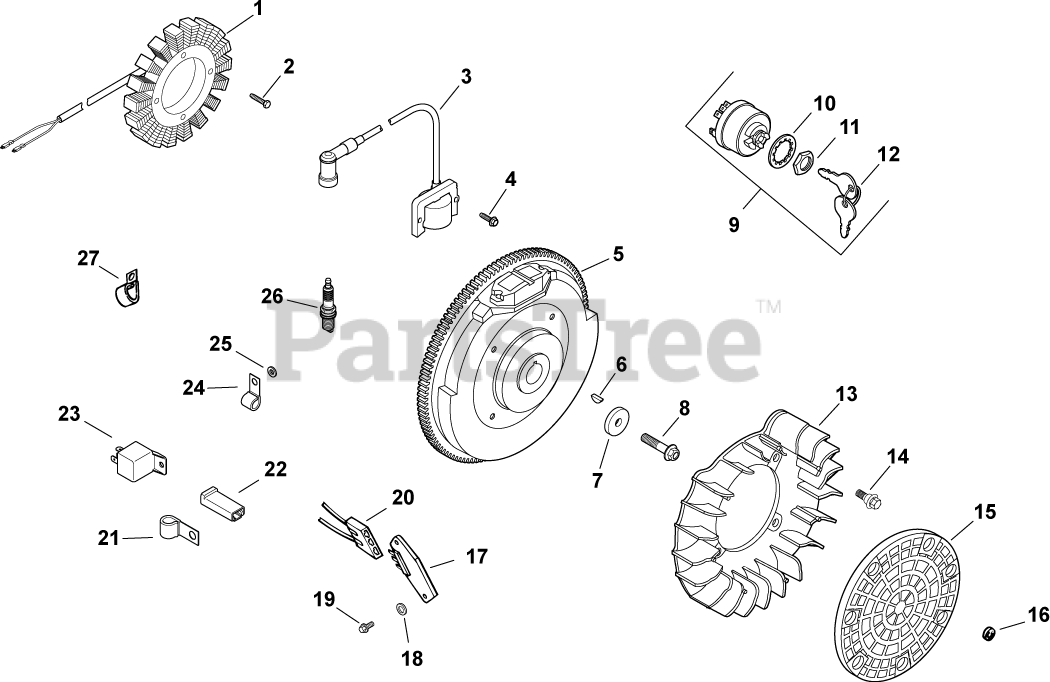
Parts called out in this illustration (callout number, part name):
1	KIT, 15 / 20 AMP STATOR
2	SCREW, M5X0.8X25 - (#25086402S)
3	KIT, MODULE IGNTN (CDI FIXED)
4	SCREW, FLG THD FRM M5X.8X20-(#25086399S)
5	FLYWHEEL, PAINTED-USE 24 025 55-S
6	KEY, 3/16" X 5/8"
7	WASHER, FLAT 13/32"
8	SCREW, FLG M10X1.5X45 - (#25086361S)
9	SWITCH ASSY, KEY (KM)-USE 25 099 32-S
10	WASHER, INTERNAL TOOTH
11	NUT, KEY SWITCH
12	KEY, SET -USE 48 340 01-S
13	FAN - USE (#24 157 11-S)
14	BOLT, SHOULDER
15	SCREEN, GRASS
17	REG/RECT-15 AMP (KM)-USE 41 403 10-S
18	WASHER, FLAT 7/32"
19	SCREW, PHL HD #11-16X7/8"
20	CONNECTOR, BODY (KM)-USE 25 155 41-S
21	CLIP, CABLE
22	CONNECTOR (1 CONTACT)
24	CLIP, CABLE
25	WASHER, FLAT 1/4" (O.D. 1/2")
26	PLUG, SPARK (STD)
27	CLIP, TUBE & WIRING (KM)
